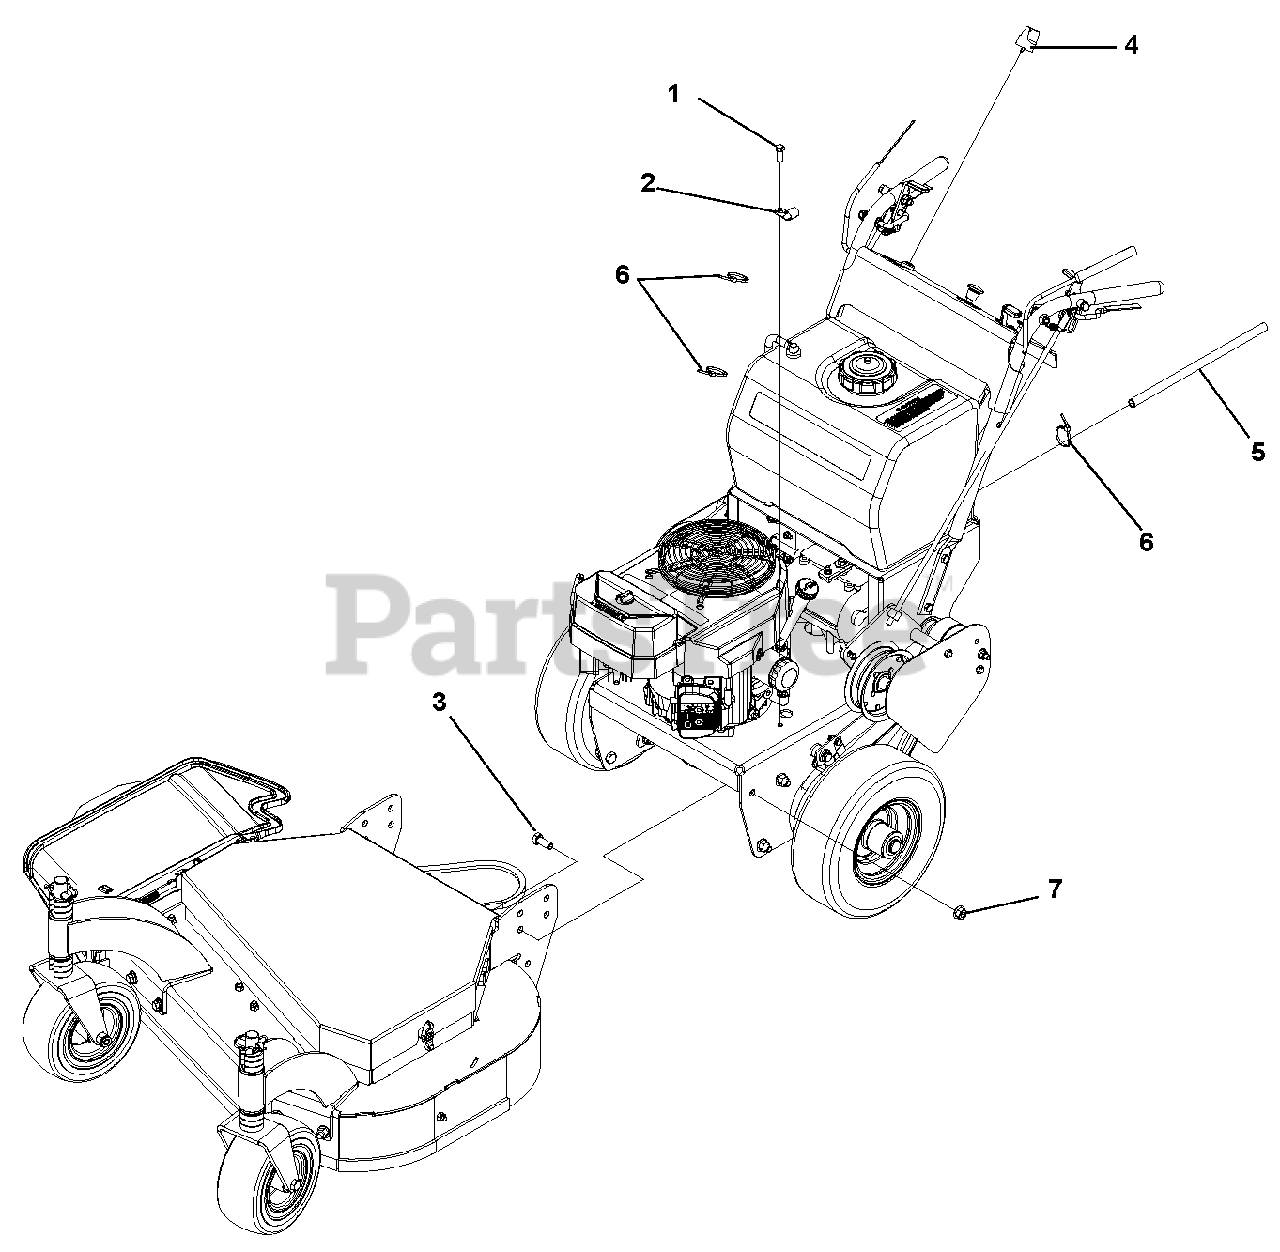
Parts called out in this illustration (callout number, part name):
1	Screw,Tapping .38-16 x .50 Hex Washer Head Thread Rolling
3	Bolt, .50-13 x 1.25 Hex 5
4	Key with Shield
5	Tube, Oil Drain 14" Clear Vinyl
6	Cable Tie, .15 x 8.50
7	Nut, .50-13 Nyloc Flange
